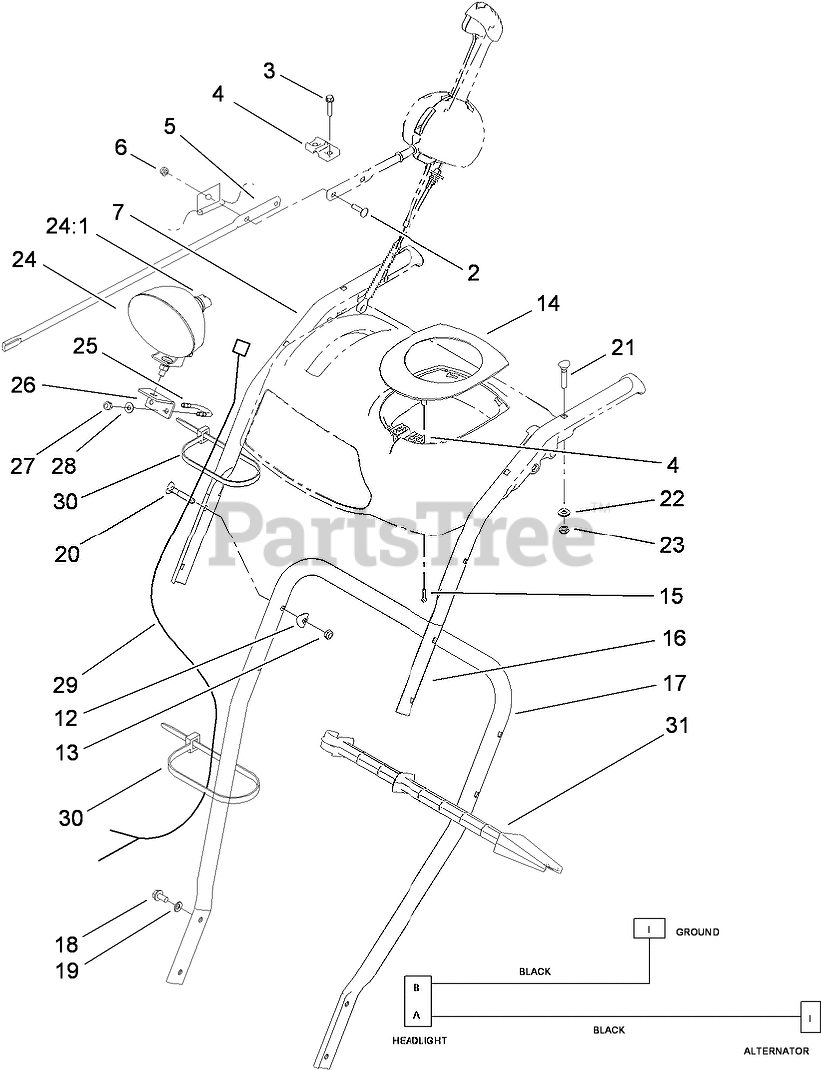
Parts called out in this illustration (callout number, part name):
2	SCREW-CARR
3	SCREW-PLASTITE
4	SUPPORT-ROD
5	ROD-CHUTE, FRONT
6	NUT-LOCK, NI
7	HANDLE-UPPER, RH
12	WASHER
13	NUT-LOCK, NI
14	COVER-PANEL, CONTROL
15	SCREW-PPH
16	HANDLE-UPPER, LH
17	HANDLE-LOWER
18	SCREW-HWHTF
19	WASHER-BELLEVILLE
20	SCREW-HANDLE
21	SCREW-HANDLE
22	WASHER-FLAT
23	NUT-LOCK, NI
24	HEADLAMP ASM
24:1	LAMP-12 VOLT
25	CLAMP
26	BRACKET-LIGHT
27	NUT-LOCK, NI
28	WASHER-FLAT
29	HARNESS-WIRE
30	TIE-CABLE
31	STICK-CLEANOUT
